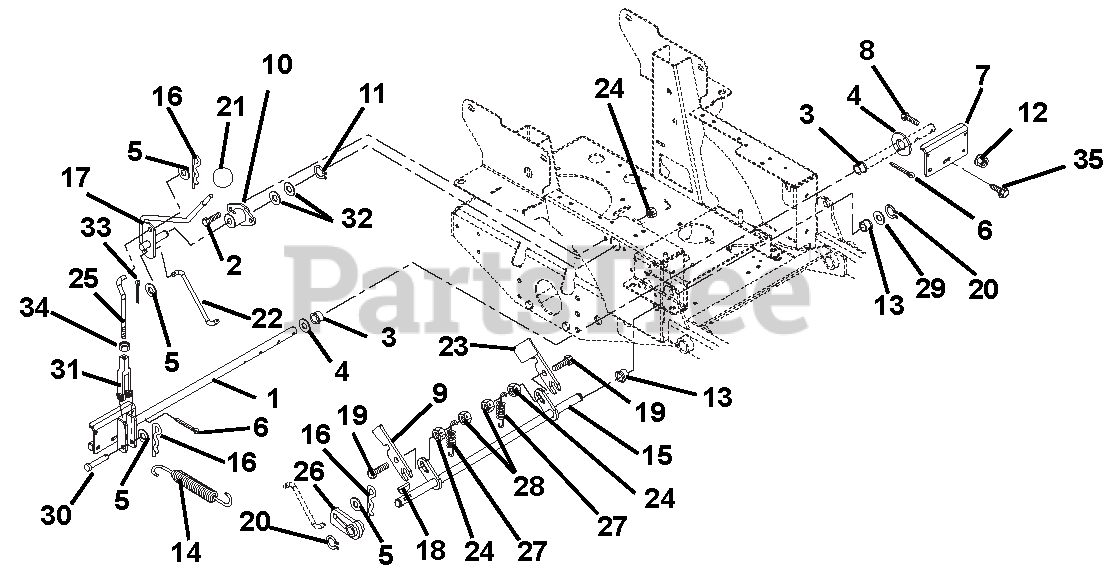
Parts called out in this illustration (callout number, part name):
1	WMT, BRAKE SHAFT
2	@BLT-HEX .31-18X1.00 GR5 YWZC
3	BSHG-FLG .762X1.0X.580X1.48 NY
4	@WSHR-FL-STL.812X1.50X.135YWZC
5	@WSHR-FL-STL.406X.812X.065 YWZ
6	@PIN-CTR .12X1.00 EXTPRSQCT YZ
7	WMT, PADDLE BRAKE
8	@BLT-HEX .25-20X1.50 GR5 YWZC
9	SLIDE, INTERLOCKING BRAKE
10	BUSHING, FLANGED
11	RG-RTNG-EXT .625X.050
12	@NUT-LK-NYL-FLG .25-20 YWZC
13	BSHG-FLG .515X.750X.745X1.00NY
14	SPRING - ENGINE - TRANS.
15	WMT, MECHANICAL BRAKE
16	PIN-HAIR, ENDRIES #25 YWZC
17	WMT, BRAKE ACTUATING
18	KEY-WDRF .13X.63 HRD#5
19	@BLT-RDHDSQNK .31-18X1.25 G5YZ
20	RG-RTNG-EXT .500X.050 (SNAP)
21	KNOB-STEERING LOCK
22	LINKAGE, BRAKE ACTUATING
23	INTERLOCK, SAFETY SWITCH
24	@NUT-LK-NYL-FLG .31-18 YWZC
25	LINKAGE, BRAKE COMPACT-Z
26	WMT, PARKING BRAKE HUB
27	SG-TENS .061 X .50 X 3.0 WLD 4
28	@NUT-LK-CTR .31-18 YWZC
29	WSHR-FL-STL .505X1.00X.062YWZC
30	PIN-CLEV .370X1.75
31	CLEVIS, .38-24 ADJ. SWIVEL
32	WSHR-FL-STL .630X1.250X.062 YZ
33	@PIN-CTR .09X.75 EXTPRSQCT YWZ
34	NUT-JAM .375-24 YWZC
35	@SCR-TAP .31-18X.75 HWH TR YWZ
